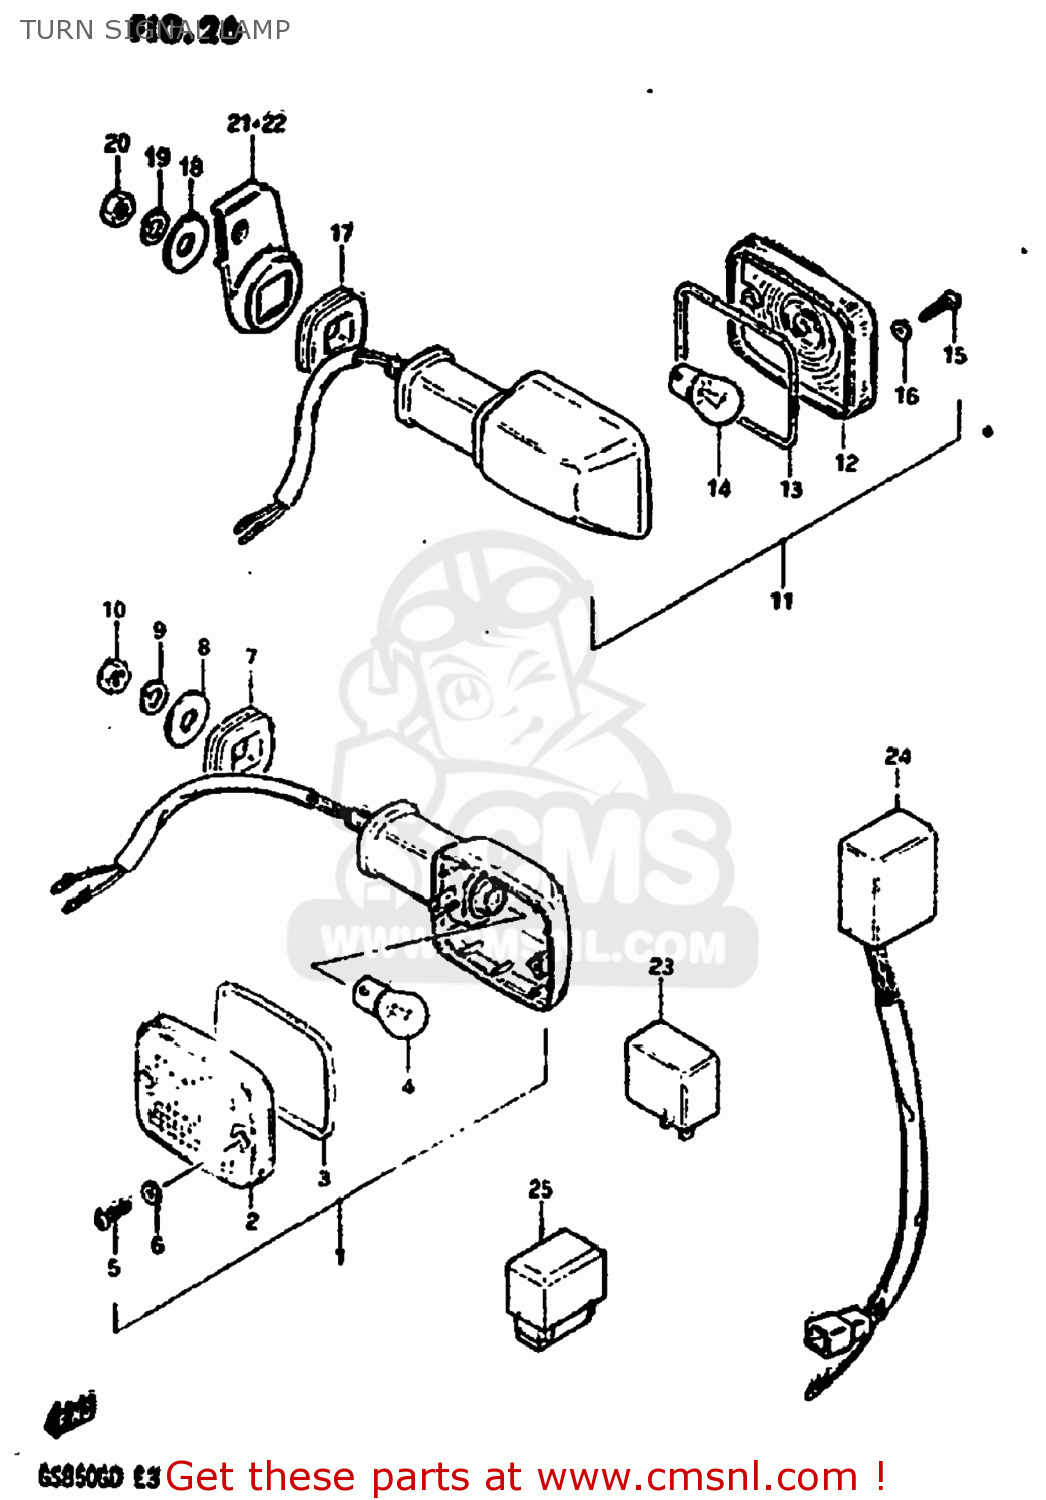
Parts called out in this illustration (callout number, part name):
1	LAMP ASSEMBLY,FRONT TURN SIGNAL
2	LENS
3	GASKET (NAS)
4	BULB(12V23W,STANLEY,A4577A)
5	SCREW
6	GASKET (NAS)
7	CUSHION
8	WASHER (10.5X30X2.3)
9	LOCK WASHER
10	NUT
11	LAMP ASSEMBLY,FRONT TURN SIGNAL
12	LENS
13	GASKET (NAS)
14	BULB(12V23W,STANLEY,A4577A)
15	SCREW
16	GASKET (NAS)
17	CUSHION
18	WASHER (10.5X30X2.3)
19	LOCK WASHER
20	NUT
21	BRACKET,REAR TURN SIGNAL
22	BRACKET,REAR TURN SIGNAL
23	RELAY ASSY,TURNSIGNAL
24	UNIT,TURN SIGNAL CONTROL
25	UNIT,TURN SIGNAL CONTROL
